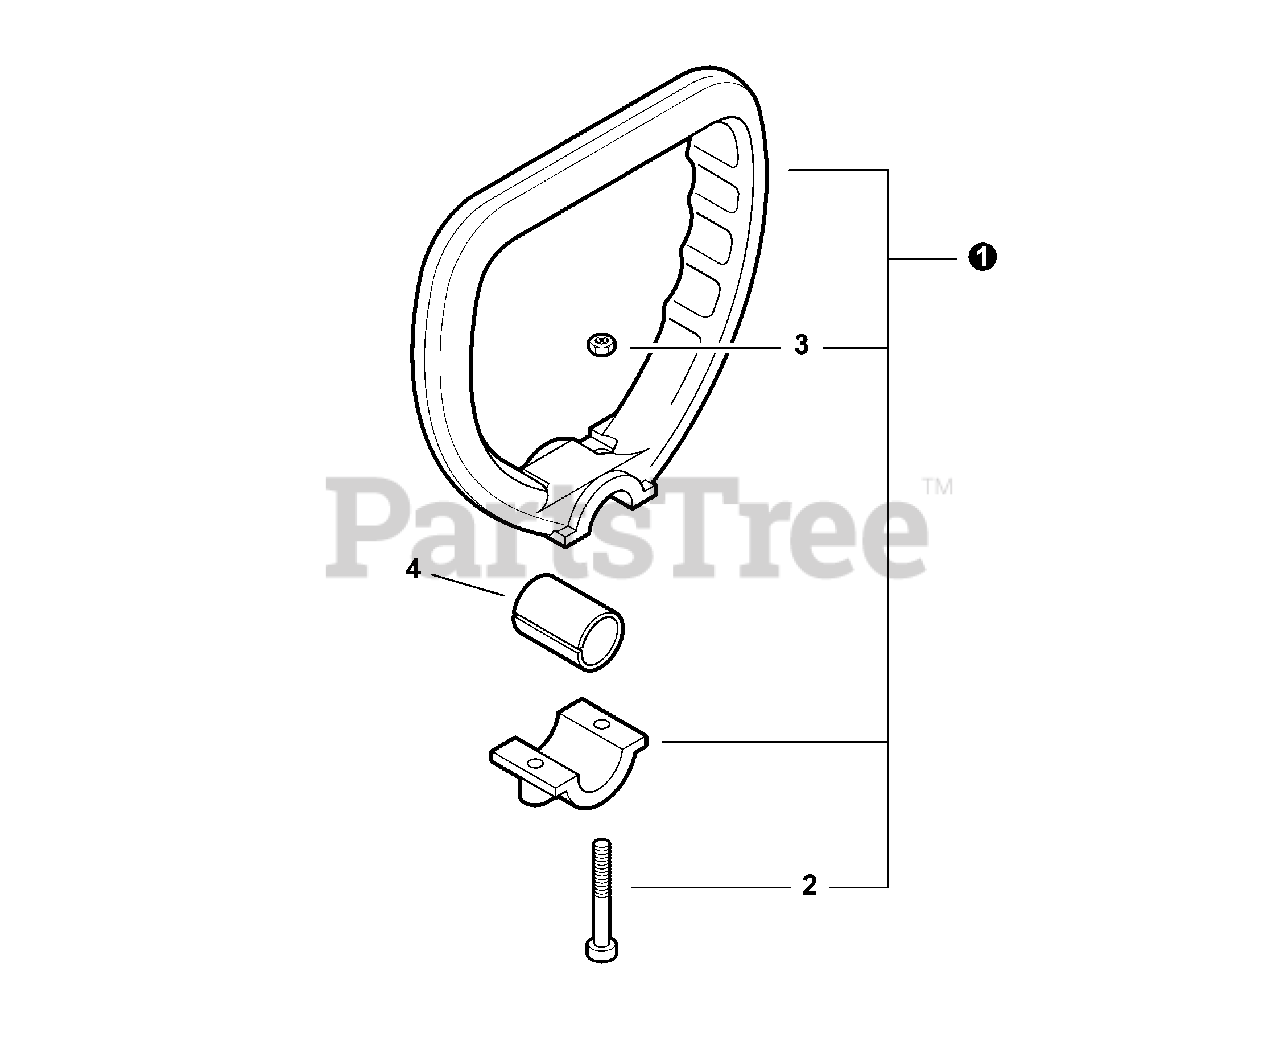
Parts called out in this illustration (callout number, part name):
1	HANDLE ASSY - SUPPORT
2	BOLT, TORX 5×35
3	NUT M5
